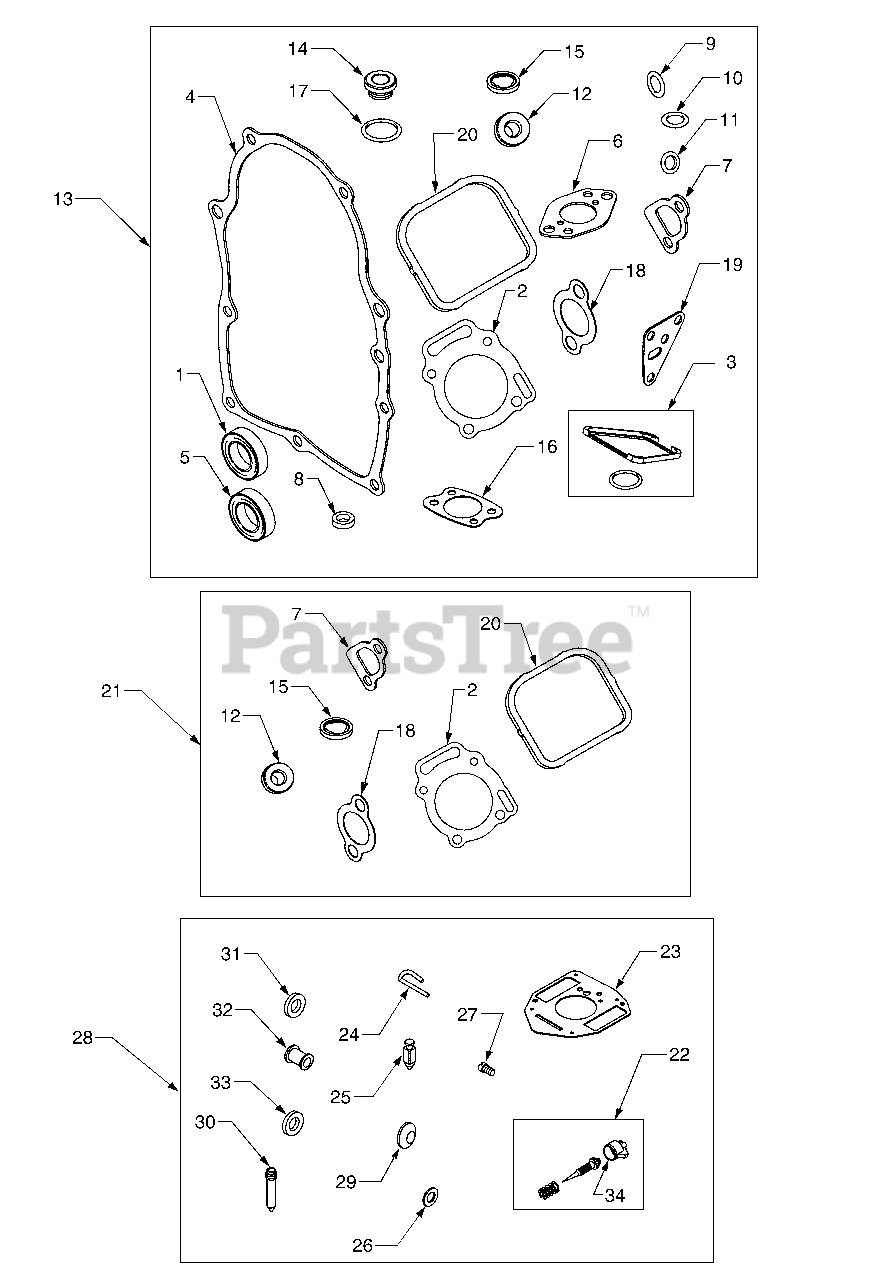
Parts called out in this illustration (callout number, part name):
1	Seal, Oil
2	Gasket, Cylinder Head
3	Gasket, Breather
4	Gasket, Crankcase
5	Seal, Oil
6	Gasket, Intake
7	Gasket, Intake
8	Seal, Governor Shaft
9	Seal, O-Ring (Crankcase Cover)
10	Seal, O-Ring (Oil Pump)
11	Seal, O-Ring (Oil Pump Screen)
12	Washer
13	Gasket Set
14	Seal, Fill Tube
15	Seal, Fill Plug
16	Gasket, Air Cleaner
17	Seal, O-ring
18	Gasket, Exhaust
19	Gasket, Filter Adapter
20	Gasket, Rocker Cover
21	Overhaul Kit, Valve
22	Valve, Idle Adjust
23	Gasket, Carburetor Body
24	Pin, Float Hinge
25	Valve, Fuel Inlet
28	Overhaul Kit, Carburetor
29	Plug, Welch
30	Nozzle, Carburetor
31	Collar, Throttle
32	Collar, Choke
33	Seal, Shaft
34	Cap, Limiter
